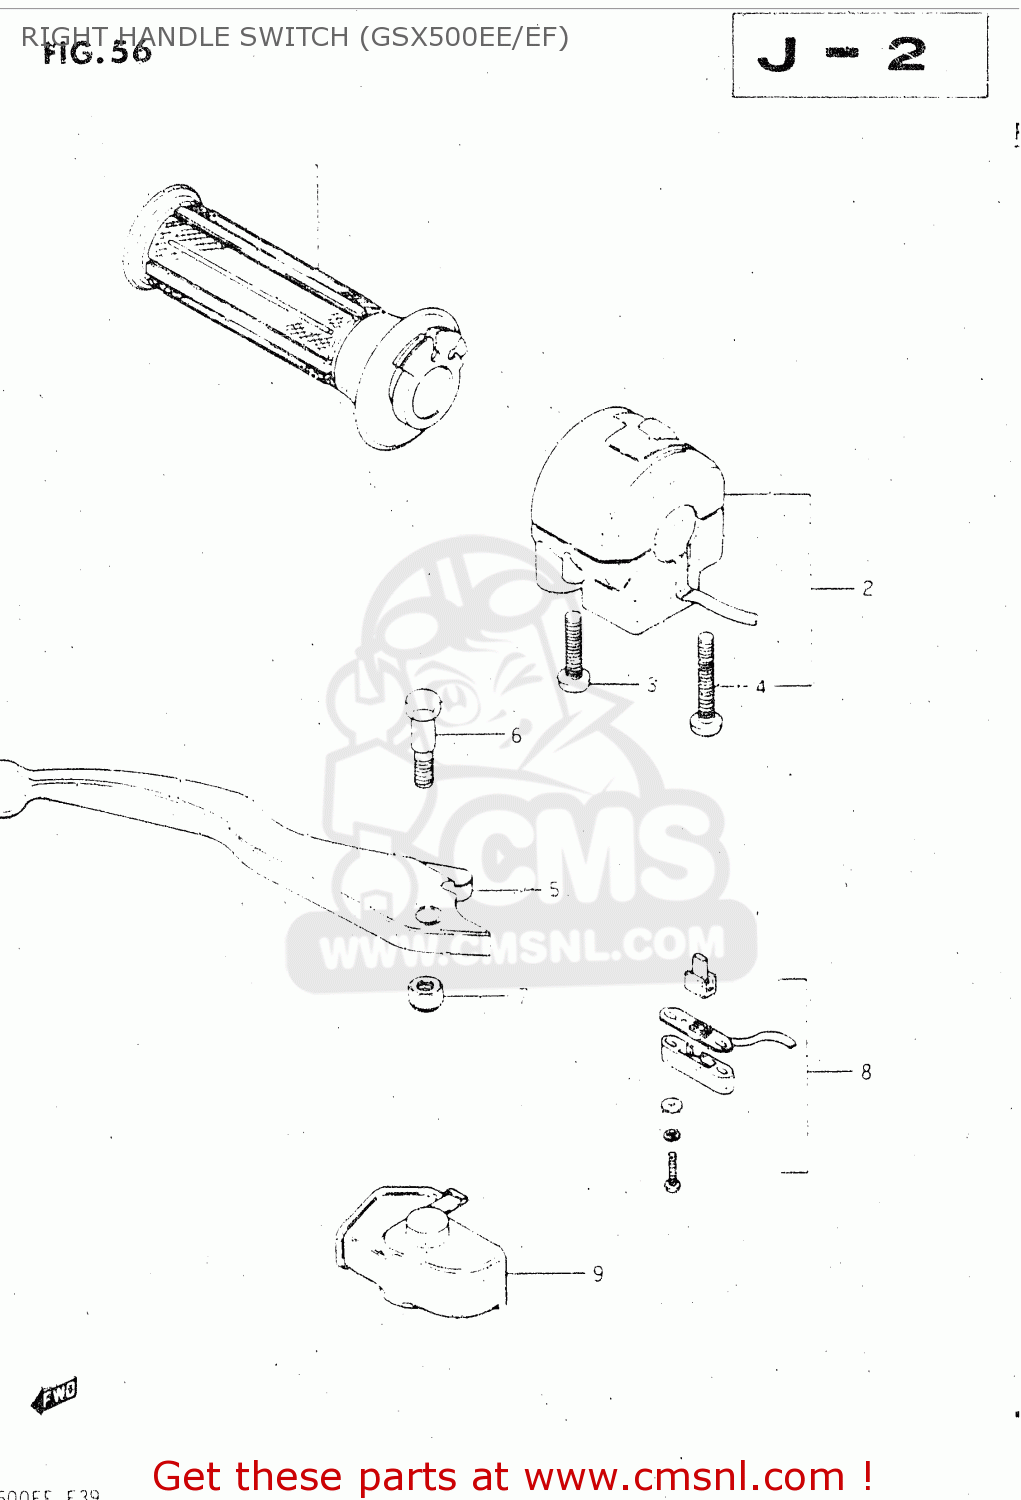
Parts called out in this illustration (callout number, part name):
1	GRIP,THROTTLE
2	SWITCH ASSY, HANDLE
3	SCREW
4	SCREW
5	LEVER,BRAKE
6	BOLT,LEVER PIVOT
7	NUT
8	SWITCH ASSEMBLY
9	COVER,BRAKE LEVER
